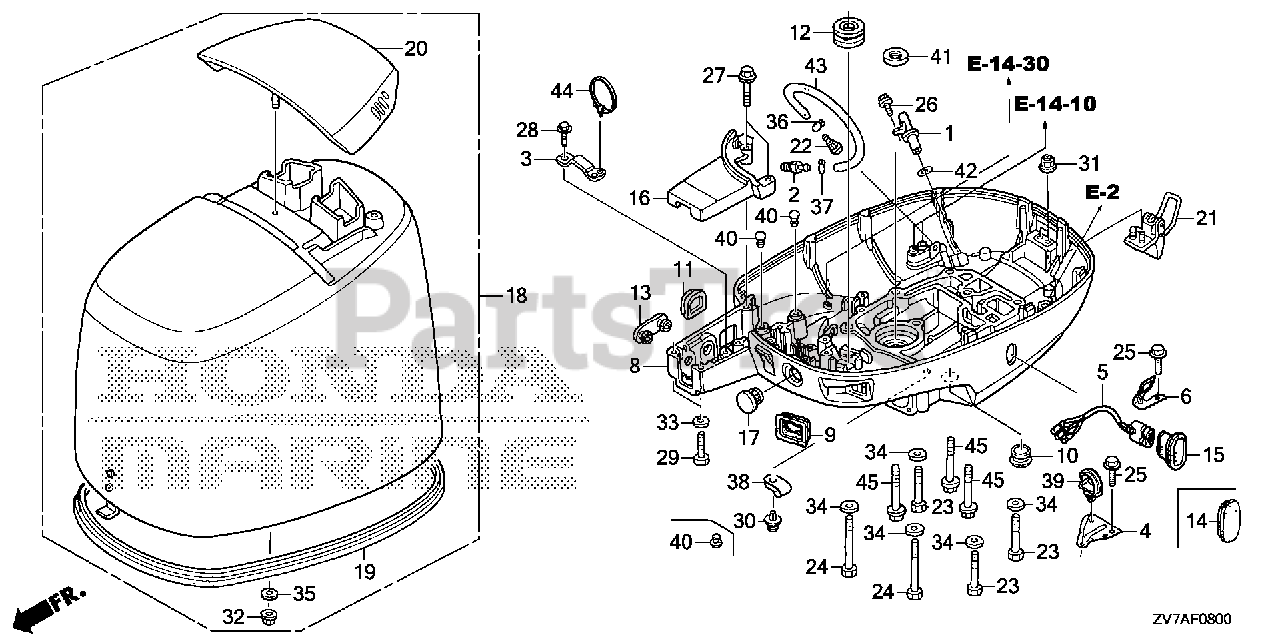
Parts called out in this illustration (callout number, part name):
1	PIPE, OIL LEVEL
2	JOINT, WATER TUBE
3	BRACKET, CABLE CLIP (S)
8	CASE, ENGINE (LOWER) *NH282MU* (OYSTER SILVER METALLIC-U)
9	GROMMET, CASE (LOWER) (B)
10	GROMMET, CASE (LOWER) (C)
11	GROMMET, CASE (LOWER) (C)
12	GROMMET, OIL CASE (E)
13	GROMMET, CASE (LOWER)
14	GROMMET, CASE (LOWER)
16	CASE, SEPARATE *NH282MU* (OYSTER SILVER METALLIC-U)
17	CAP, HANDLE (LOWER)
18	COVER, ENGINE *NH282MU* (OYSTER SILVER METALLIC-U)
19	SEAL, ENGINE COVER
20	HANDLE, TILT *NH282MU* (OYSTER SILVER METALLIC-U)
21	LEVER, FASTENER
22	GROMMET, WATER CHECK
23	BOLT, HEX. (8X55)
24	BOLT, HEX. (8X80)
26	BOLT, FLANGE (6X12) (CT200)
27	BOLT, FLANGE (6X28) (CT200)
28	BOLT, FLANGE (5X10) (CT200)
29	BOLT, HEX. (6X45)
31	NUT, SELF-LOCK (6MM)
32	NUT, U (6MM) (FUSE RASHI)
33	WASHER, PLAIN (6MM)
34	WASHER, PLAIN (8MM)
35	WASHER (6MM)
36	CLIP, TUBE (B8)
37	CLIP, TUBE (B10)
40	PLUG, CHANGE REINFORCEMENT
41	SEAL, WATER (17X26X7)
42	O-RING (11.5X3.5)
43	TUBE, WATER CHECK
44	CLIP, HARNESS BAND (145MM) (BLACK)
45	BOLT, FLANGE (8X70)
